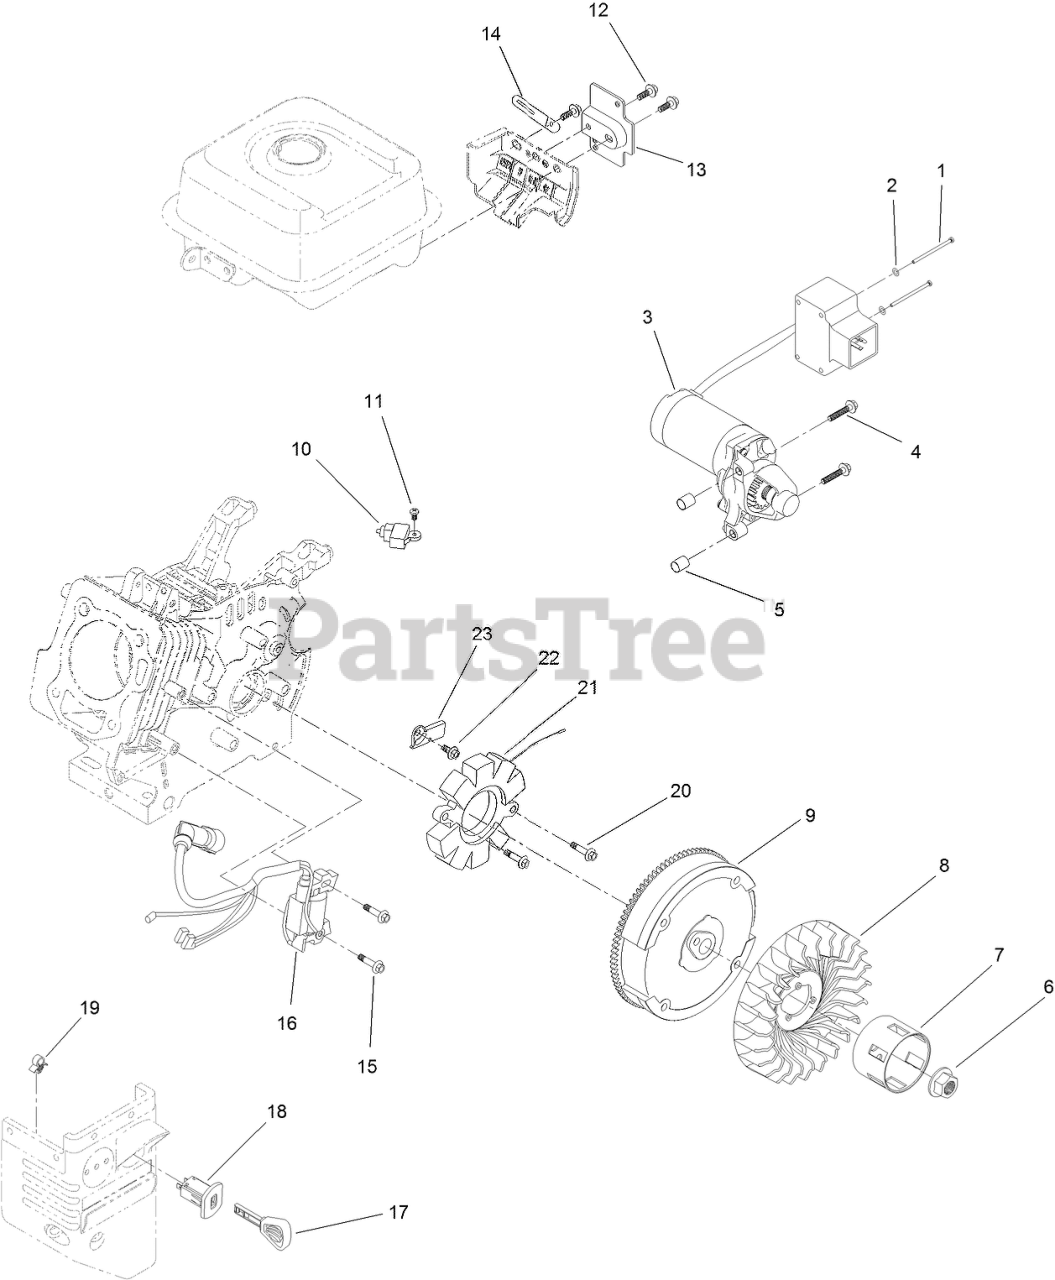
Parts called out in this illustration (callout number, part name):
1	SCREW-BHP
2	WASHER-PLAIN
3	MOTOR-STARTER
4	SCREW-FLANGE
5	PIN-DOWEL
6	NUT-FLANGE
7	CUP-STARTER
8	FAN-COOLING
9	FLYWHEEL ASM
10	SWITCH-KILL, ENGINE
11	SCREW-PPH
12	SCREW-HHF
13	BRACKET-SWITCHBOX, STARTER
14	CLIP-HARNESS, WIRE
15	SCREW-HHF
16	IGNITION COIL ASM
18	SWITCH-KEY
20	SCREW-HHF
21	ALTERNATOR
22	SCREW-HHF
23	CLAMP-WIRE, CHARGE
